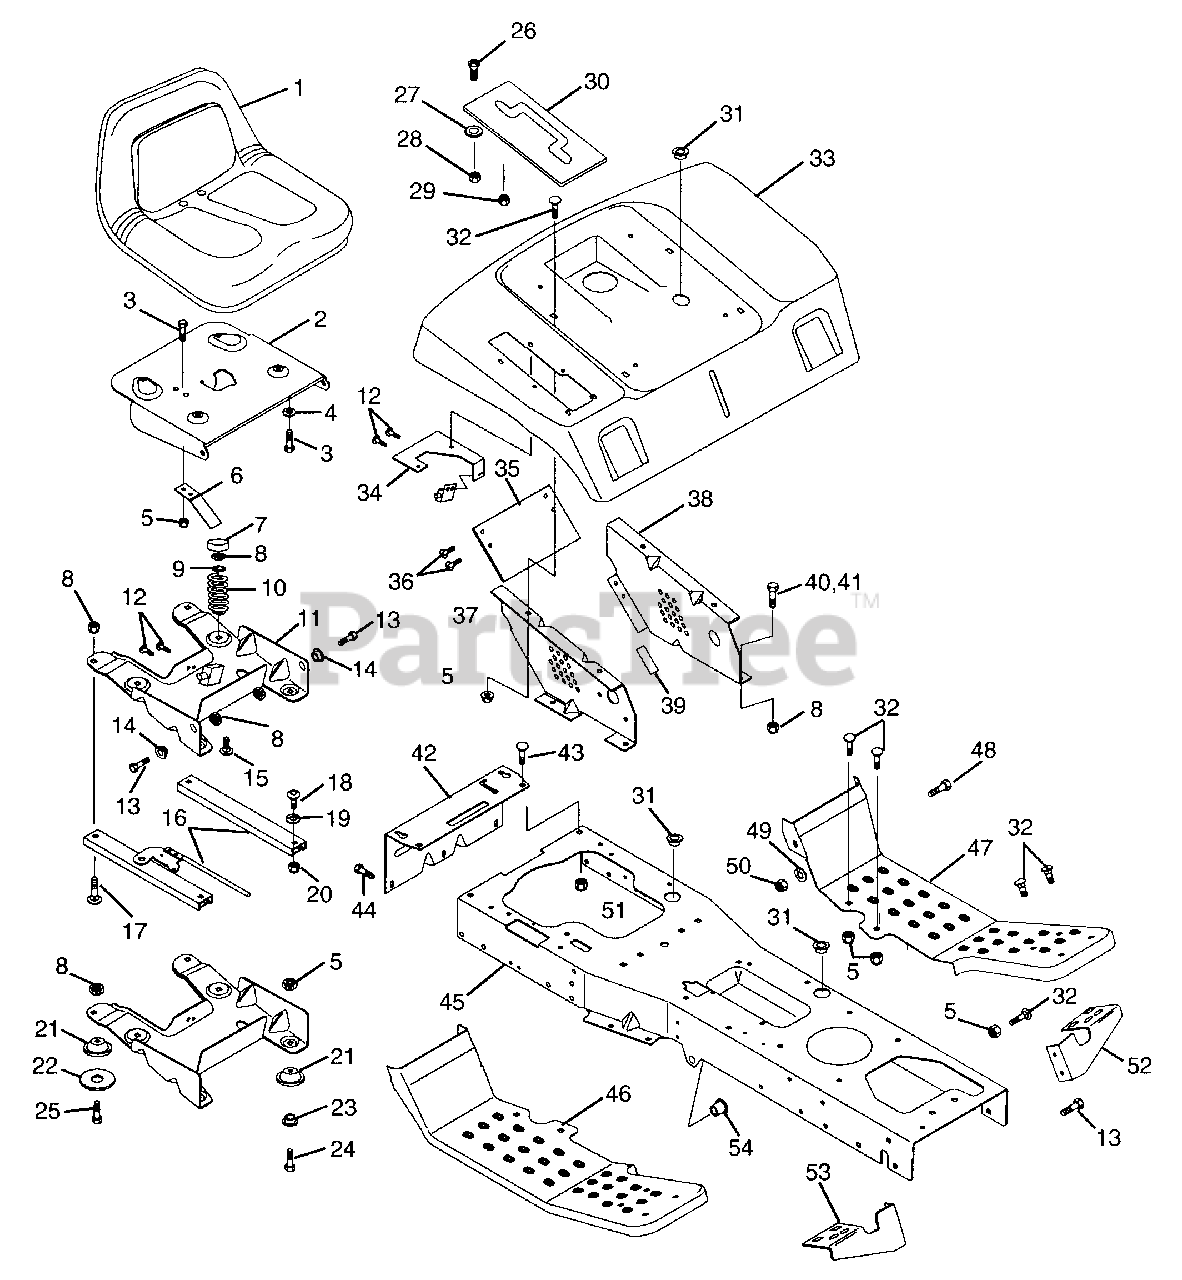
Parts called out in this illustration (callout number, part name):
1	SEAT- V-560
1	SEAT- V450
2	SEAT PIVOT PLATE
3	BLT-HEX .31-18X.75 PL GR2
4	WSHR-LK .312X.097 PL HVY
5	NUT-FLG. .312-18 PL
6	SPRING PLATE
7	TUBE CAP
8	NUT-LK .312-18 GR A PL
9	WSHR-FL-STL.344X.688X.065PL
10	SG-COMP .148X1.23X2.41 WLD87
11	BOX, SEAT
12	SCR-TAP 12-24X.50 HWH PL TR
13	BLT-HEX .31-18X.75 PL GR5
14	BSHG-FLG .325X.465X.333X.685
15	BLT-RDHDSQNK.31-18X.75GR5SHTPL
16	SEAT SLIDES -(RAME TAK-3010-4)
17	WSHR-LOCK .875 MED PL
18	SCR-CAP BTHD.31-18X.50 GR5 YZ
19	WSHR-LK-EXT .313X.030 PL
20	NUT-HEX .312-18
21	SEAT SPACER
22	WSHR-FL-STL .508X1.62X.105 PL
23	BSHG-FLG .325X.500X.513X.875
24	BLT-HEX .31-18X1.25 PL GR2
25	BLT-RDHDSQNK .31-18X1.00 PL
26	SCR-MCH .25-20X .75 CRFL PL
27	WSHR-FL-STL.281X.62X.065 PL
28	NUT-LK-NYL .250-20 PL
29	NUT-SELF-THRDNG FITS.25 STUDPL
30	SHIFT INSERT ASSY- 5 SPEED
30	SHIFT INSERT ASSY- 6 SPEED
30	SHIFT INSERT ASSY- HYDRO
31	SNAP BUSHING
32	BLT-RDHDSQNK .312-18X.62SHTPL
33	REAR DECK- YT
33	REAR DECK - LT
34	SWITCH MOUNT
35	BACK PLATE
36	SCR-TAP 10-12X.50 CRPH PL A BL
37	RIGHT DECK SUPPORT
38	LEFT DECK SUPPORT
39	FOAM TAPE
40	BLT-HEX .31-18X.63 PL GR 2
41	BLT-HEX .31-18X1.00 PL GR 2
42	DRAW BAR
43	BLT-RDHDSQNK .375-16X.75 GR5PL
44	SCR-TAP .312-18X.75 HWH PL TR
45	MAIN FRAME
46	RIGHT FOOT REST
47	LEFT FOOT REST
48	BLT-HEX .25-20X.63 PL GR2
49	WSHR-LK .250X.077 HVY PL
50	NUT-HEX .250-20 PL
51	NUT-LK-CTR .375-16 GR A PL
52	LH FOOT REST BRACE
53	RH FOOT REST BRACE
54	BSHG-FLG .515X.750X.745X1.00NY
